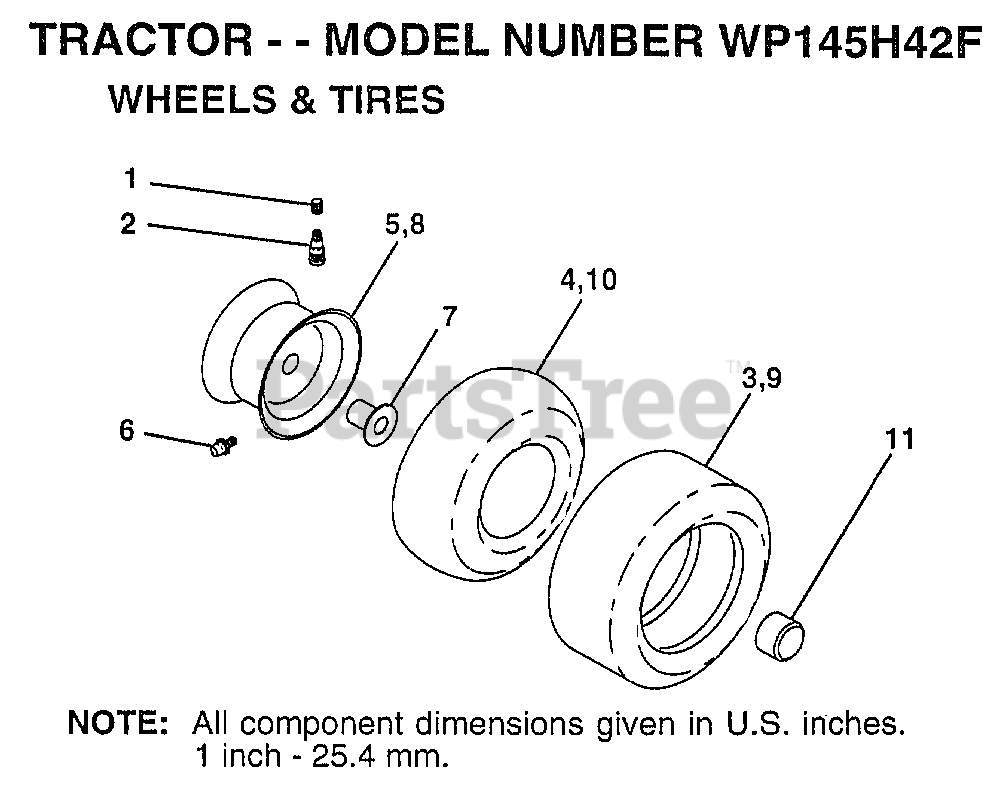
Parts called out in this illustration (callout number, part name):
1	VALVE CAP
2	VALVE STEM LT
4	TUBE.5.3/4.5/6
5	"RIM,FRT T"
6	FITTING LT
7	"FLANGE, BEARING"
8	"RIM 8"""
9	TIRE.20X8-8
10	TUBE.18X9.5-8
11	HUB CAP
